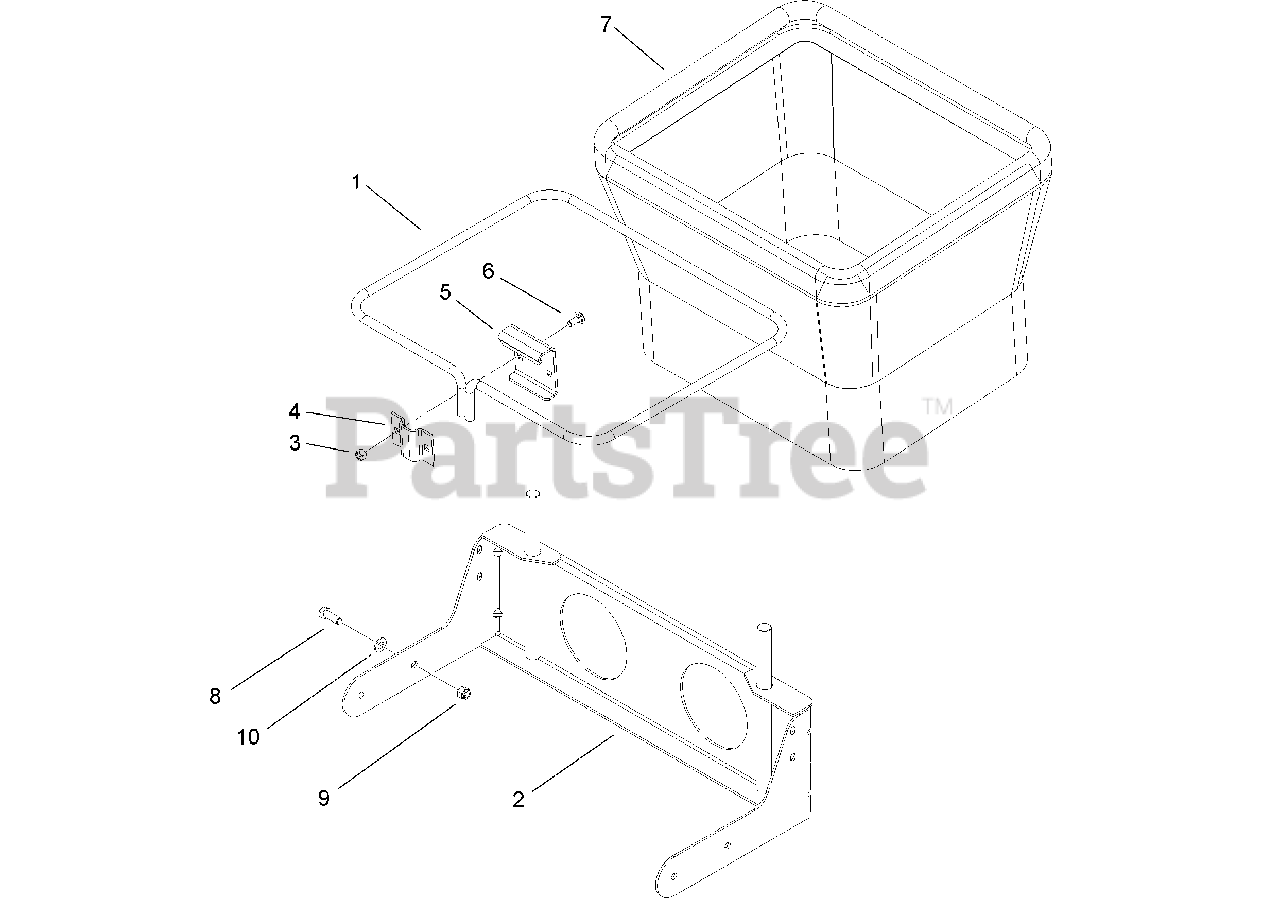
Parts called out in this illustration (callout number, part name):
1	FRAME-BAG
2	BAGGER SUPPORT ASM
3	NUT-LOCK, NI
5	HANGER-BAG
6	BOLT-CARR
8	SCREW-HH
9	NUT-LOCK, NI
10	WASHER-FLAT
